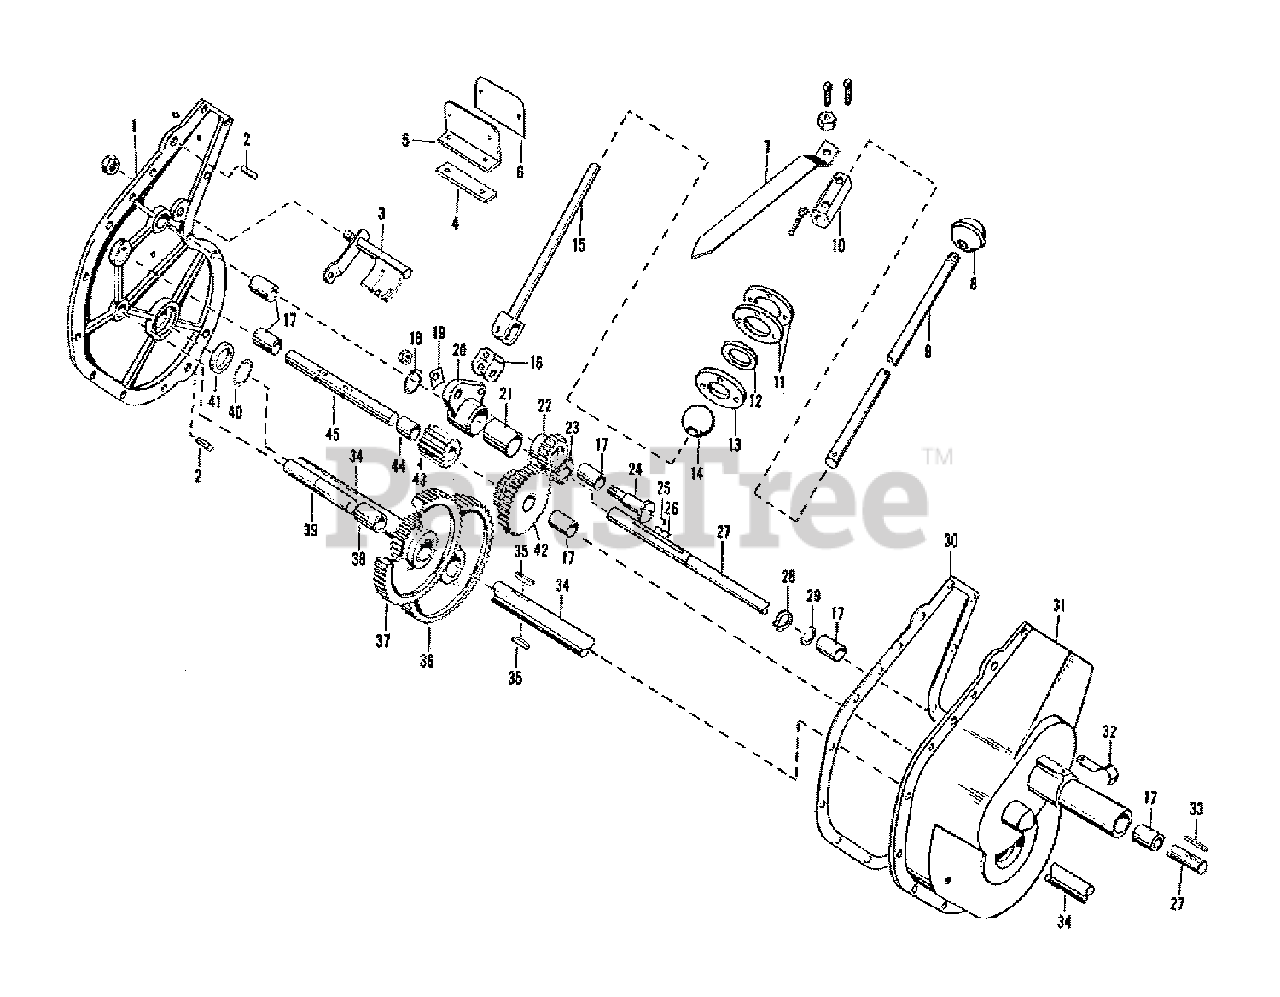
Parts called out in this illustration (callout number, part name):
1	GEAR CASE COVER
2	DOWEL PIN
3	SHIFT GUIDE ASSEMBLY
4	SHIFT INST. PLATE BRACKET HOLDER
5	SHIFT INST. PLATE BRACKET HOLDER
6	SERIAL AND SHIFT INSTRUCTIONS PLATE
7	SHIFTER POINTER
8	SHIFT LEVER BALL
9	GEAR SHIFT HANDLE Ext.
10	GEAR SHIFT HANDLE COUPLING
11	SHIFT BALL SPACER
12	SHIFT BALL WAHSER
13	GEAR SHIFT BALL RETAINER
14	GEAR SHIFT BALL
15	PITMAN CELVIS ASSEMBLY
16	PITMAN, Gear Shift
17	BEARING, Bronze
18	RING, Retaining
19	PLATE, Lock
20	ROCKER ARM ASSEMBLY
21	BEARING, Rocker Arm
22	PINION, Rocker Arm with Bearings
23	TRANSMISSION SLIDE GEAR
24	PIN, Rocker Arm Pinion
25	SLIDE KEY LOCK PLATE
26	TRANSMISSION SLIDE KEY
27	TRANSMISSION PULLEY SHAFT
28	RING, Retaining
29	WASHER, Spacer
30	GEAR CASE GASKET
31	GEAR CASE
32	LATCH, Idler Lever
33	PULLEY KEY, Tranmsission
35	KEY, Axle
36	DRIVE GEAR
37	CLUSTER GEAR ASSEMBLY
38	BUSHING, Intermediate, 5/8 x 3/4 x -7/16"
39	SPINDLE, Intermediate
40	RING, Retaining
41	WASHER, Retaining
42	CLUSTER GEAR ASSEMBLY
43	GEAR, High
44	SPACER, Transmission Pinion Shaft
45	TRANSMISSION PINION SHAFT
